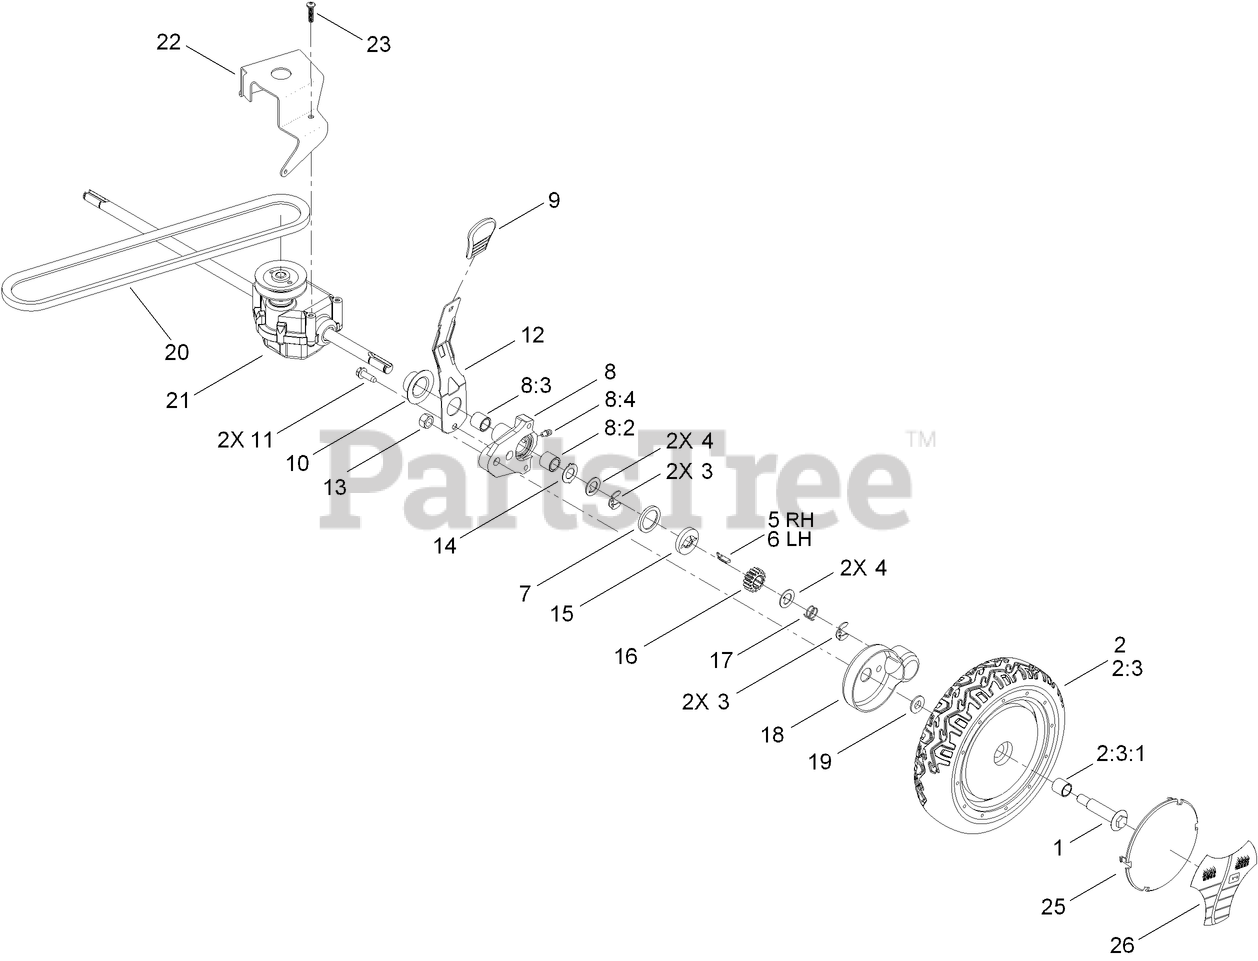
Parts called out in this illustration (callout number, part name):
1	BOLT-SHOULDER
2	8 INCH WHEEL AND GEAR ASM
2:3	Loose Parts Package
2:3:1	BUSHING
3	RING-RETAINING,CLIP
4	WASHER-THRUST, KEYED
6	KEY-ROCKING, LH
7	RING-FRICTION
8	PIVOT ARM ASM
8:2	BUSHING
8:3	BUSHING
8:4	FITTING-GREASE
9	KNOB-HOC
10	CAP-END
11	SCREW-HWHTF
12	ARM-SPRING
13	LOCKNUT
14	WASHER-ARM, PIVOT
15	WASHER-CLUTCH
16	GEAR-PINION
17	SPRING-COMPRESSION
18	COVER-WHEEL
19	SPACER-COVER, WHEEL
20	V-BELT
22	BRACKET-TRANSMISSION
23	SCREW-PLASTITE
25	COVER-WHEEL
26	LABEL-WHEEL, SMART
